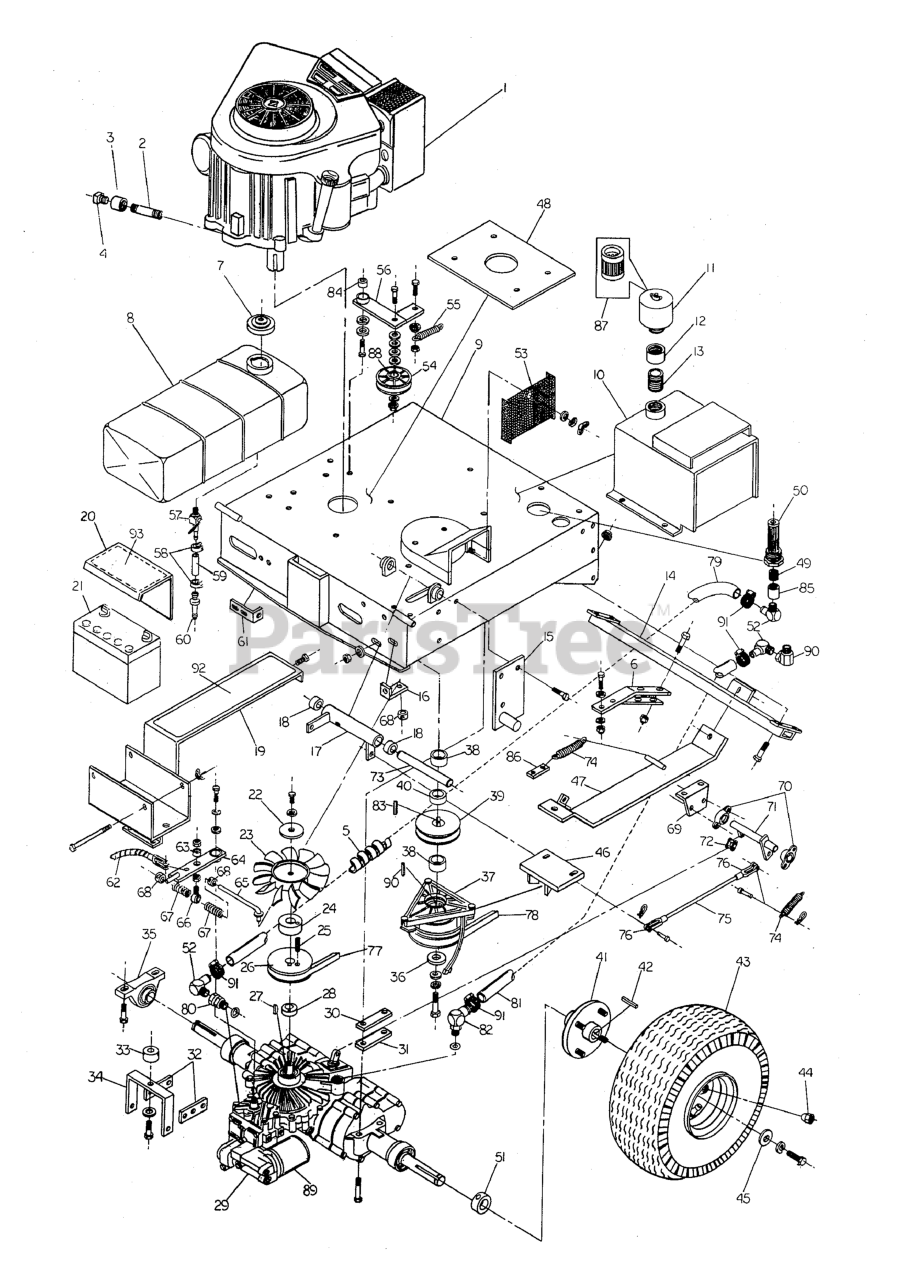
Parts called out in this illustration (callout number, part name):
2	Pipe Nipple
3	Coupler
4	Pipe Plug
5	Plastic Hose Coil
6	Torque Arm
7	Gas Cap
8	Fuel Tank, 4 Gallon
8	Gas Tank Strap
9	Engine Deck
10	Hydro Tank
11	Air Filter Assembly
12	1" Coupler
13	Close Nipple
14	Engine Deck Cross Member
15	Pivot Bracket - LH
15	Pivot Bracket - RH
16	Spring Anchor
17	Parking Brake Bell Crank
18	BUSHING, Brass
19	Gas Tank Mount
20	Battery Cover
21	BATTERY, Lawn & Garden, 12V (BCIU1, 340 CCA)
22	WASHER, 5/16" Fender
24	Fan Pulley Spacer
25	Roller Pin
26	PULLEY (3/4" Bore)
27	KEY, #61 Woodruff
28	Hydro Input Pulley Spacer
29	850 Transaxle
30	1/4" Spacer (Red)
31	3/16" Spacer (Black)
32	BRACKET, Transmission Support
33	SPACER, .39 x 1.75 x .88
34	Transmission Torque Bracket
35	BEARING, PILLOW BLOCK, 1
36	SPACER, .45 x 1.62 x .37
37	CLUTCH, Electric, 1" Shaft
38	SPACER, 1.13 X 2.00 X .37
39	PULLEY, Crankshaft
40	SPACER, 1.13 X 1.50 X .50
41	DRIVE HUB DETAIL
42	KEY, 1/4 SQ. X 2-1/2
43	TIRE & WHEEL ASSEMBLY, 18 X 8.5 X 8
44	LUG NUT, 1/2-20
45	Retaining Spacer
46	Electric Clutch Anchor
47	Skid Plate
48	Engine Plate
49	NIPPLE, 1/2" NPT Close
50	STRAINER
51	COLLAR, 1" Split
52	FITTING, 90 Degrees 1/2" NPT
53	Hydro Intake Screen
54	Idler Pulley
55	SPRING, Extension
56	IDLER ARM ASSEMBLY, Complete
57	Fuel Shut-Off Valve
58	CLAMP, Hose
59	Fuel Line
60	FUEL FILTER
61	CABLE BRACKET
62	CABLE, Speed Control
63	SPACER, .38 x .50 x .27
64	TRANSMISSION CONTROL ARM
65	ROD, NEUTRAL SPRING WELDMENT
66	BALL JOINT, 3/8-24 Male
67	SPRING, Compression
68	COLLAR, 5/16" Set
69	Bearing Mount Parking Brake
70	BEARING, Flange
71	Parking Brake Jackshaft
72	CONNECTOR, #50 Chain Link
73	3/4" Shaft
74	SPRING, Extension
75	Linkage Rod
76	CLEVIS, 5/16-24, Plastic
77	BELT, A-Section
78	Belt 48" Deck
79	Inlet Hose
80	FITTING, 7/8" O-Ring Straight Swivel
81	Return Hose
82	FITTING, 90 Degrees 7/8" O-Ring
83	KEY, 1/4" SQ. X 1-1/4
84	SPACER, .32 x .75 x 1.06
85	COUPLER, 1/2" NPT
86	Dump Valve Lever
87	Air Filter Element
88	INSERT, Bearing
89	FILTER, Transmission Oil
90	FITTING, 1/2 NPT Swivel, 90 Deg.
91	CLAMP, #10 Hose
92	Gas Tank Safety Walk
93	SAFETY WALK
